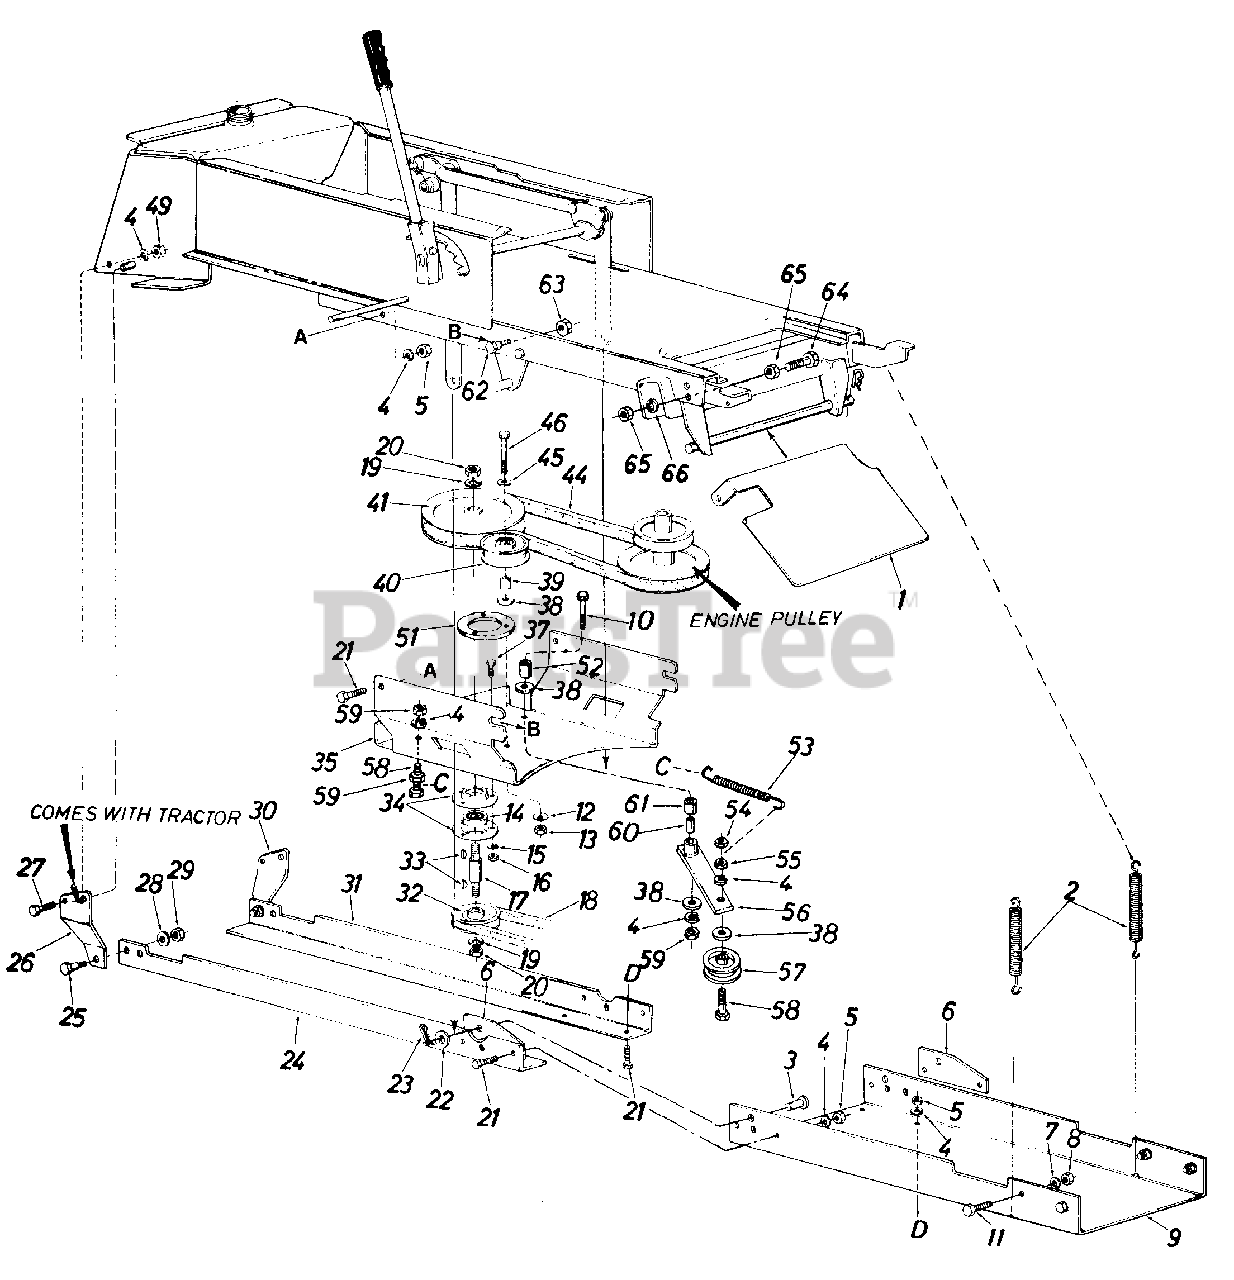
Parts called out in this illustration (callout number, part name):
1	Guide Bracket
2	Helper Spring
3	Clevis Pin
4	L.-Wash. 3/8" I.D.*
5	Hex L.-Nut 3/8-2 Thd.
6	Attaching Plate
7	L.-Wash. 1/2" I.D.*
8	Hex L.-Nut 1/2-2 Thd.
9	Front Support Channel
10	Hex Bolt 3/8- 1 6 x 3. 75 " Lg.
11	Hex Bolt 1/2-20x 1.25" Lg.*
12	Belleville Wash.3/8" I.D.
13	Hex L.-Nut 3/8-16 Thd.
14	Ball Bearing
15	L.-Wash. 5/16" I.D.*
16	Hex Nut 5/16-18 Thd.*
17	Spindle
18	"V"-Belt 1/2" x 88" x 2 (Kevlar)
19	L.-Wash. 5/8" I.D.*
20	Hex Jam Nut 5/8-11 Thd.
21	Hex Bolt 3/8-24 x 1.00" Lg.*
22	Flat Washer
23	Internal Cotter Pin
28	Fl.-Wash. .44" I.D. x 1.38" O.D. x .130
29	Hex L.-Nut 7/16-24 Thd.
30	Rear Hanger Brkt. - L.H.
33	#6 Hi-Pro Key 3/16 x 5/8" D ia.
34	Bearing Housing
35	Supporting Bracket
37	Hex Sems Bolt 5/16-18 x 1.00" Lg.*
38	Fl.-Wash. .38" I.D. x 1.00" O.D. x .135
39	Spacer.38" I.D. x .62" O.D.
40	Fl.-Idler Pulley
41	Upper Drive Pulley
44	"V"-Belt 1/2" x 49.8" Lg.
45	F l.-Wash.
46	Hex Bolt 3/8-16 x 2.50" Lg.*
49	Hex Nut 3/8-16 Thd.*
53	Extension Spring .54" O.D. x 4.75" Lg.
54	Hex Cent. L.-Nut 3/8-16 Thd.
55	Hex Jam Nut 5/8-11 Thd.
56	Idler Arm Ass'y.
57	Idler Pulley
58	Hex Bolt 3/8-16 x 2.25" Lg.
59	Hex Jam Nut 3/8-16 Thd.
60	Spacer.377" I.D. x .60" O.D. x.830" Lg.
61	Spacer.380" I.D. x .630" O.D. x.565" Lg.
62	Shoulder Bolt.498 Dia. x.340
63	Hex Cent. L.-Nut 3/8-16 Thd.
64	Hex Bolt 1/4-28 x 1.5" Lg.*
65	Hex Nut 1/4-28 Thd.*
66	L-Wash. 1/4" I.D.*
